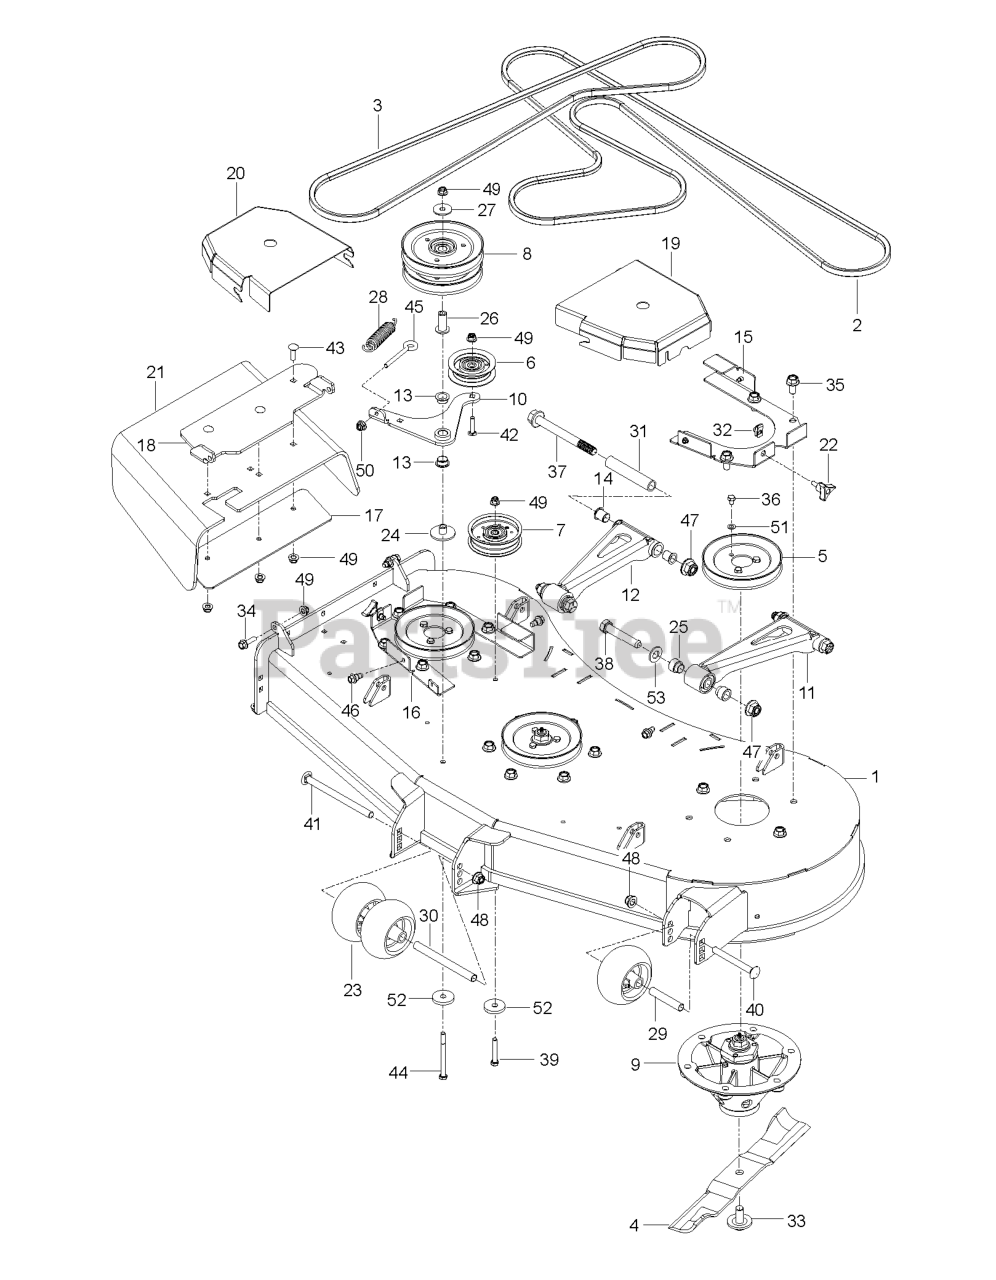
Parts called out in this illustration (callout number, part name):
1	DECK.WLDT.54"CCC.STANDON X668
2	BELT STANDON 54 CCC DECK
3	BELT.DECK.DRIVE.STAND-ON
4	BLADE STANDON 54 CCC DISCHARGE
5	PULLEY - 6.57
6	PULLEY.IDLER.FLAT.3.06"
7	PULLEY.IDLER.FLAT.4"
8	PULLEY.STANDON.54CCC.STACKED
8	Bearings
9	SPINDLE.ASSY.IRON
10	ARM STANDON WELDMENT; DECK TEN
11	ARM STANDON LH DRAWBAR WELDMEN
12	ARM STANDON 54 CCC RH DRWBR
13	BEARING FLANGED; PLASTIC 5/8"
14	BEARING FLANGED;PLASTIC 7/8" I
15	BRACKET STANDON 54 CCC LH PULL
16	BRACKET STANDON 54 CCC RH PULL
17	BRACKET STANDON LOWER DEFLECTO
18	BRACKET STANDON UPPER DEFLECTO
19	COVER STANDON 54 CCC LH PULLEY
20	COVER STANDON 54 CCC RH PULLEY
21	DEFLECTOR STANDON MOLDED DECK
22	KNOB W/STUD
23	ROLLER, GAUGE .635 BORN
24	SPACER STANDON DECK TENSIONER
25	SPACER STANDON DRAWBAR BEARING
26	SPACER STANDON STACKED PULLEY
27	SPACER STANDON STACKED PULLEY
29	TUBE, ROLLER AXLE
30	TUBE, ROLLER AXLE LONG
31	TUBE STANDON DRAWBAR SPACER
32	U-CLIP 5/16-18 NUT RETAINER
33	BLADE BOLT/WASHER
34	HHFS 3/8-16 X 1.25 GD 5
35	HHFS 1/2-13 X 1 GR5 ZD
36	HCS 5/16-18 X 1/2 GR 5 ZD
37	BOLT HEXAGON HEAD WITH FLANGE
38	5/8-11 X 3-1/2 HHB GRADE 5
39	BOLT.HEX
40	RHSNB 1/2-13 X 4.75 GR5 ZD
41	RHSNB 1/2-13 X 8 GR5 ZD
42	RHSNB 3/8-16X1-3/4
43	BOLT.3/8-14X1.25
44	BOLT HEXAGON HEAD 3/8-16 X 4-1
45	EYE BOLT 5/16 X 3.50
46	BOLT.SHOULDER
47	NUT 5/8-11 FLG NYLOC ZD
48	NUT, 1/2-13 HEX FLG NYLOC ZD
49	NUT 3/8-16 HEX FLG NYLOC ZD
50	5/16-18 NYLOC FLANGE NUT
51	WASH 5/16 DISC SPRING ZD
52	SPINDLE WASHER
53	WASHER
